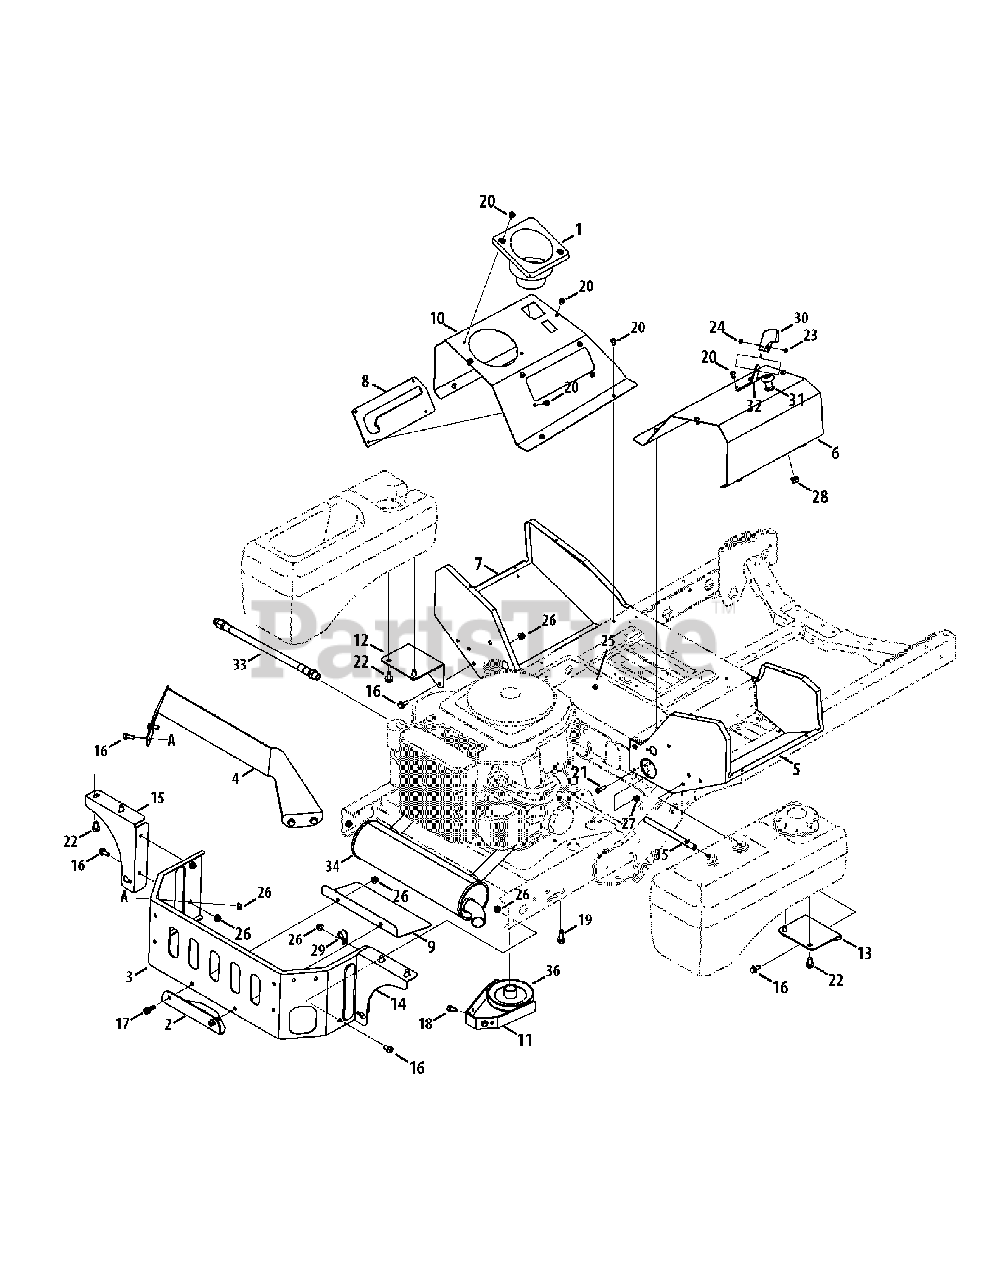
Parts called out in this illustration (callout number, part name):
1	Cup Holder
2	Hitch Bracket
3	Bumper Bracket
4	Upper Bumper Bracket
5	RH Lower Console
6	RH Upper Console
7	LH Lower Console
8	Parking Brake Lock Bracket
9	Muffler Mount Bracket
13	Right Tank Support Bracket
17	Hex Flange, 5/16-18 x 1.0
18	Hex Washer Screw, 5/16-18 x .750
19	Screw, 3/8-16 x 1.00
20	Screw, 1/4-20 x .5
21	Screw, 1/4-20 x 1.0
22	Hex Washer Screw, 3/8-16 x .500
23	Machine Screw, #8-32 x0.375
24	Hex Nut, #8-32
25	Sems Nut, 1/4-20
26	Flange Lock Nut, 5/16-18
27	Flange Lock Nut, 1/4-20
28	Flange Lock Nut, 3/8-16
29	Clamp, 9/16
30	Throttle Knob
31	Choke Cable
32	Throttle Cable, 39.0 x .62
33	Oil Drain
34	Kohler Muffler
36	Electric PTO Engine Pulley
